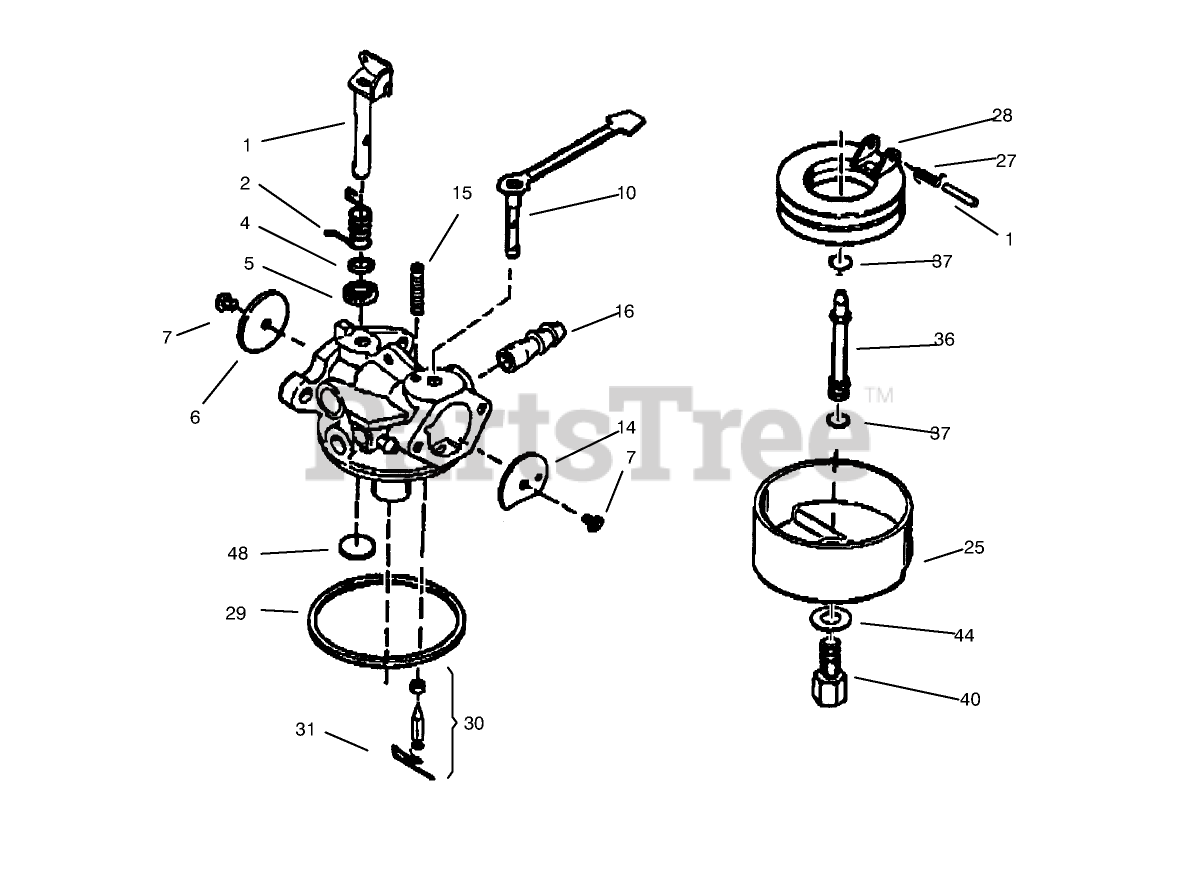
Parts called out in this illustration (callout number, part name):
1	Throttle Shaft and Lever ASM
2	Spring-Trottle, Return
4	Washer-Seal, Dust
5	Seal-Dust
6	Shutter-Throttle
7	Screw-Shutter
10	Choke Shaft and Lever ASM
14	Shutter-choke
15	Spring-Positioning, Choke
16	Fitting-Fuel
25	Bowl Float
26	Spring-Float, Dampening
27	Shaft-Float
28	Float
29	O Ring-Bowl, Float
30	Inlet Needle, Seat Clip Assy. (Incl. No. 13)
31	Clip-Spring
36	Tube-Nozzle, Main
37	O-Ring
40	Nut-Bowl, High Speed
44	Washer-Bowl Nut
48	Plug-Welch, Atmospheric Vent
